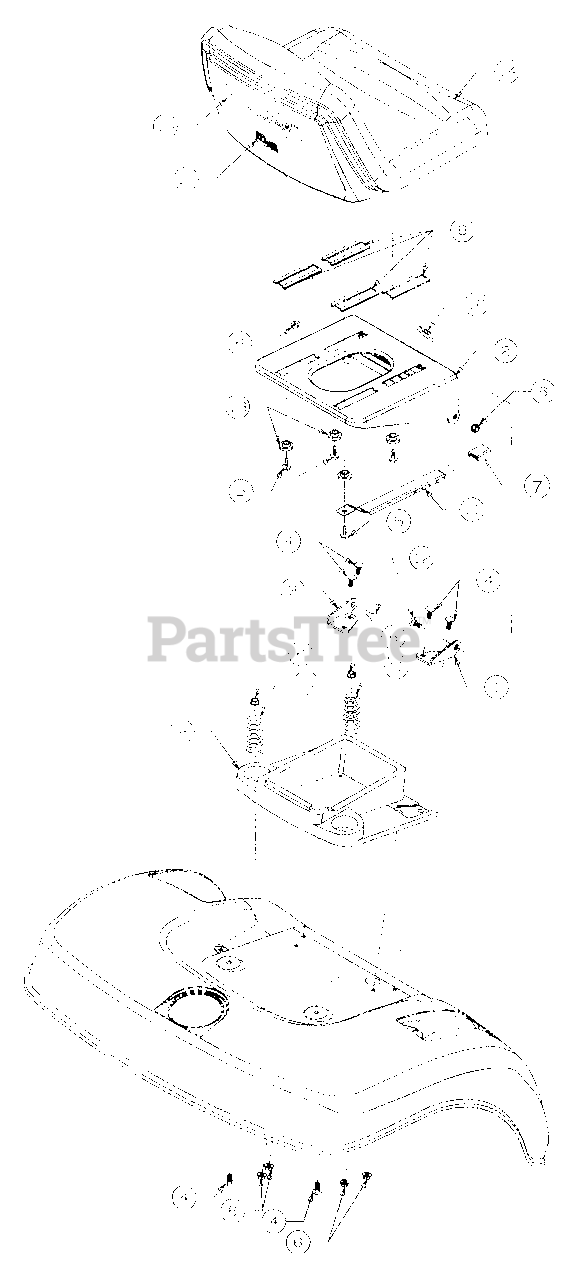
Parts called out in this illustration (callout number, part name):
5	Screw, Hx Wsh Hd Tap 5/16-18 x .75
6	Nut, Hex Flange Lock, 5/16-18
7	Knob, Seat Adjuster
8	Slide, Seat
9	Tray, Tool
10	Spring, Comp, 1.9 OD x 2.4
11	Adjuster, Seat
12	Bolt, Shoulder
13	Spacer, Shoulder
14	Seat, High Back
15	Graphic, Seat Back
16	Graphic, Seat Adjuster
17	Graphic, Made in USA
